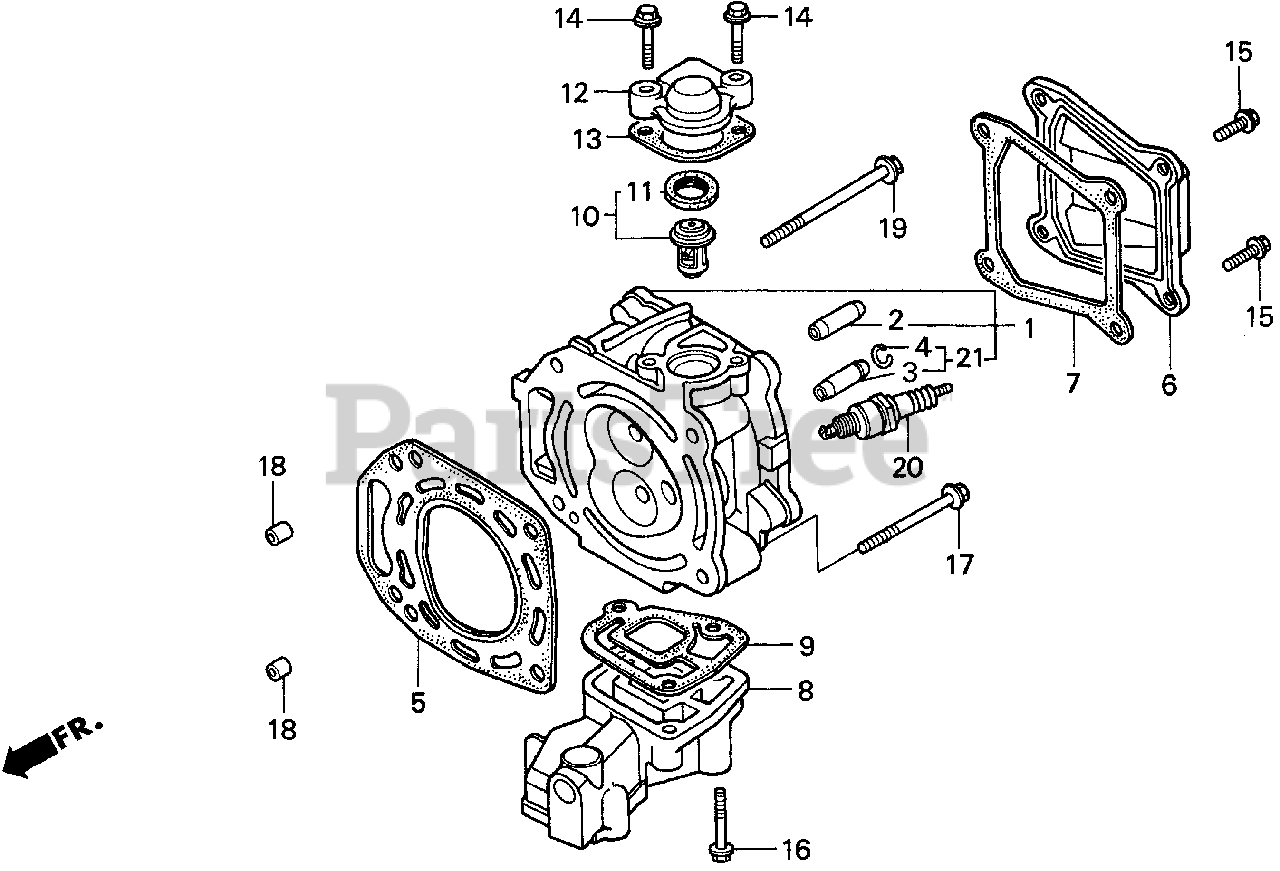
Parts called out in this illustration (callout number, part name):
1	CYLINDER HEAD
2	GUIDE, VALVE (OS)
4	CLIP, VALVE GUIDE
5	GASKET, CYLINDER HEAD
6	COVER, HEAD
7	GASKET, CYLINDER HEAD COVER
8	MANIFOLD, EX.
9	GASKET, EX. MANIFOLD
10	THERMOSTAT ASSY.
11	RUBBER, THERMOSTAT
12	COVER, THERMOSTAT *NH8* (DARK GRAY)
13	GASKET, THERMOSTAT COVER
14	BOLT, FLANGE (6X23)
15	BOLT, FLANGE (6X12)
16	BOLT, FLANGE (6X32)
17	BOLT, FLANGE (8X60)
18	PIN A, DOWEL (10X16)
19	BOLT, FLANGE (8X90)
20	SPARK PLUG (BPR5ES) (NGK)
20	SPARK PLUG (W16EPR-U) (DENSO)
